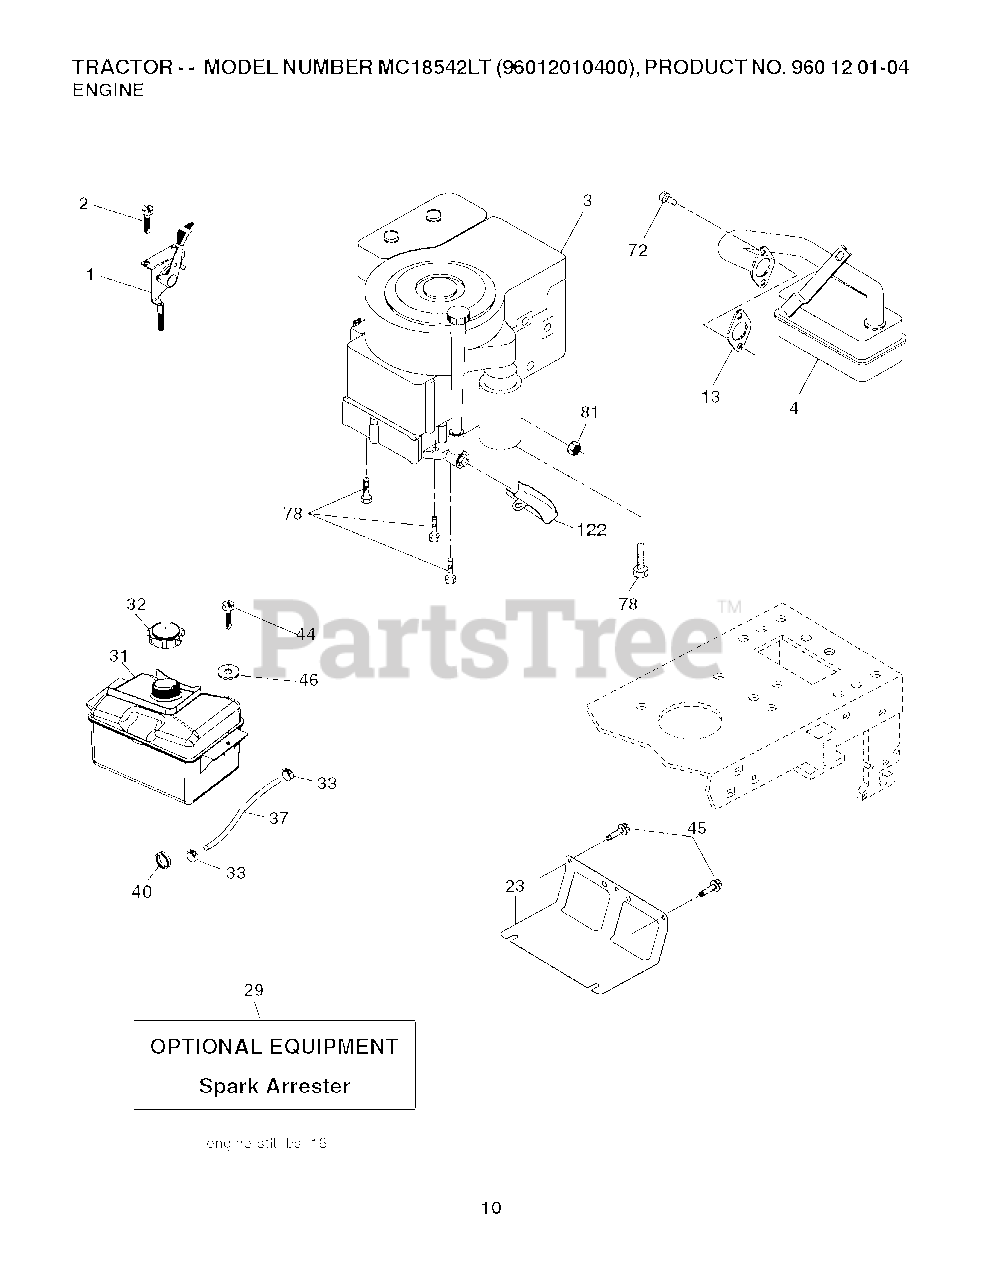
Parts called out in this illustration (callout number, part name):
1	CONTROL.THROTTLE/CHOKE.BLACK
2	SCREW
3	Poulan TBD
4	MUFFLER.LT.BRIGGS.14HP.IC/OHV
23	SHIELD.BROWNING.DBR.GUARD
29	KIT.SPARK ARRESTOR(392390 B&S)
31	RP TANK FUEL FRT 1.5 GAL
32	CAP ASM.FUEL.2.25"FR.
33	HOSE CLAMP
37	LINE.FUEL.20"FRONT.EMI
40	GROMMET T
44	SCREW HEXWSHR 1/4-20X3/4
45	SCREW, 3/8-16X3/4
72	SCREW.SOCKET HD.5/16-1
78	SCREW.3/8-16
81	NUT
122	EXTENSION DRAIN OIL
